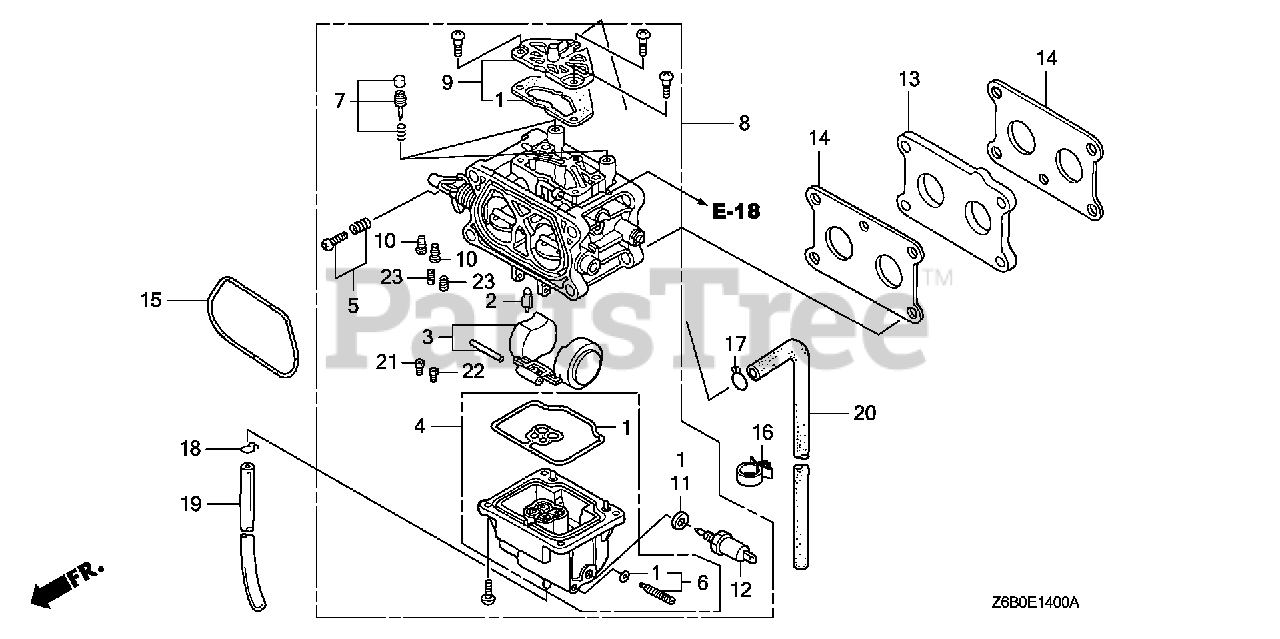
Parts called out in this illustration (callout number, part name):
1	GASKET SET
2	VALVE, FLOAT
4	CHAMBER SET, FLOAT
6	SCREW SET, DRAIN
7	SCREW SET, PILOT
8	CARBURETOR ASSY. (BW04A C)
9	COVER SET, AIR VENT
12	VALVE ASSY., SOLENOID
13	INSULATOR, CARBURETOR
14	GASKET, INSULATOR
15	GASKET, AIR CLEANER
16	CLIP, WIRE HARNESS
17	CLIP, TUBE (B8)
18	CLIP, TUBE (B6.5)
19	BULK HOSE, VINYL (4X7X8000) (95003-07(95003-07001-60M) (CARBURETOR NO.)
20	BULK HOSE, VACUUM (4.5X1000) (4.5X450) (BULK HOSE 95005-45008-10M)
21	JET, MAIN (#71.3)
21	JET, MAIN (#73.8)
21	JET, MAIN (#76.3)
22	JET, MAIN (#73.8)
22	JET, MAIN (#76.3)
22	JET, MAIN (#78.8)
23	JET, PILOT (#35)
